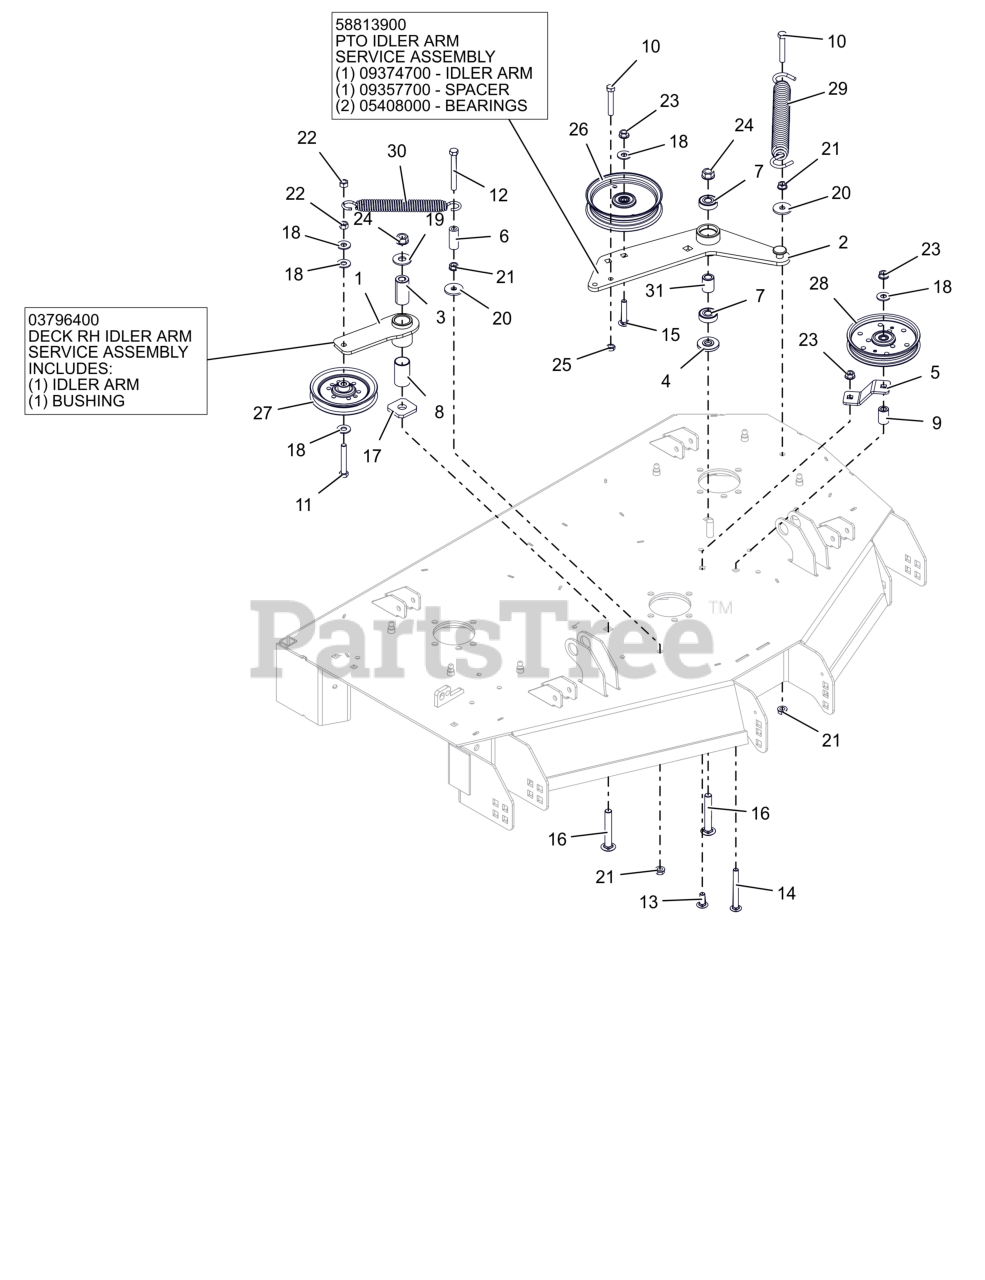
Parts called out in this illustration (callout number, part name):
1	WMT, IDLER ARM - BLACK
1	ASM, IDLER ARM (DECK)
2	WLDMT, IDLER ARM PT660
2	PTO IDLER ARM
2	SPACER .510 X .867 X 1.1485
2	BRG-BALL .500X1.38X.437
3	BSHG, SPCR .502X.997X2.03 PM
4	SPACER, IDLER ARM
5	PTO FIXED IDLER MTG BRKT -RED
6	HOSE, .38 X 1.65
7	BRG-BALL .500X1.38X.437
8	BSHG, 1.00X1.125X1.937
9	BUSHING, SLV .380X.750X1.190
10	BLT,HEX .38-16X2.25 G5 ZCC
11	BLT, HEX .38-16X2.50 G5 ZCC
12	BLT, HEX .38-16X3.25 G5 ZCC
13	BLT,RHSSN .38-16X1.00 G5 ZCC
14	BLT,RHSSN .38-16X3.50 G5 ZCC
15	BLT,RHSSN.375-16X2.00 G5 ZCC
16	BTL,RHSSN .500-13 X 3.25 G5 ZCC
17	WSHR-FLT .640X1.75X.250
18	WSHR,FLT .438X1.00X.083 ZCC
19	WSHR,FLT .563X1.375X.109 ZCC
20	WSHR,FLT .406X1.375X.135 ZCC
21	NUT, SPNLK-FLG .38-16 G5 ZCC
22	NUT-LK-CTR .38-16 ZC120
23	NUT-LK-CTR-FLG .375-16 GF ZCC
24	NUT-LK-CTR-FLG .500-13 GG ZCC
25	NUT-JAM .375-16 G2 ZCC
26	IDLER- FLAT - 5.00" X .75"
27	IDLER, V, 5.00X.38
28	IDLER- 5" FLANGED
29	SPRING, EXTENSION
30	SPRING- EXTENSION
31	SPACER .510 X .867 X 1.1485
